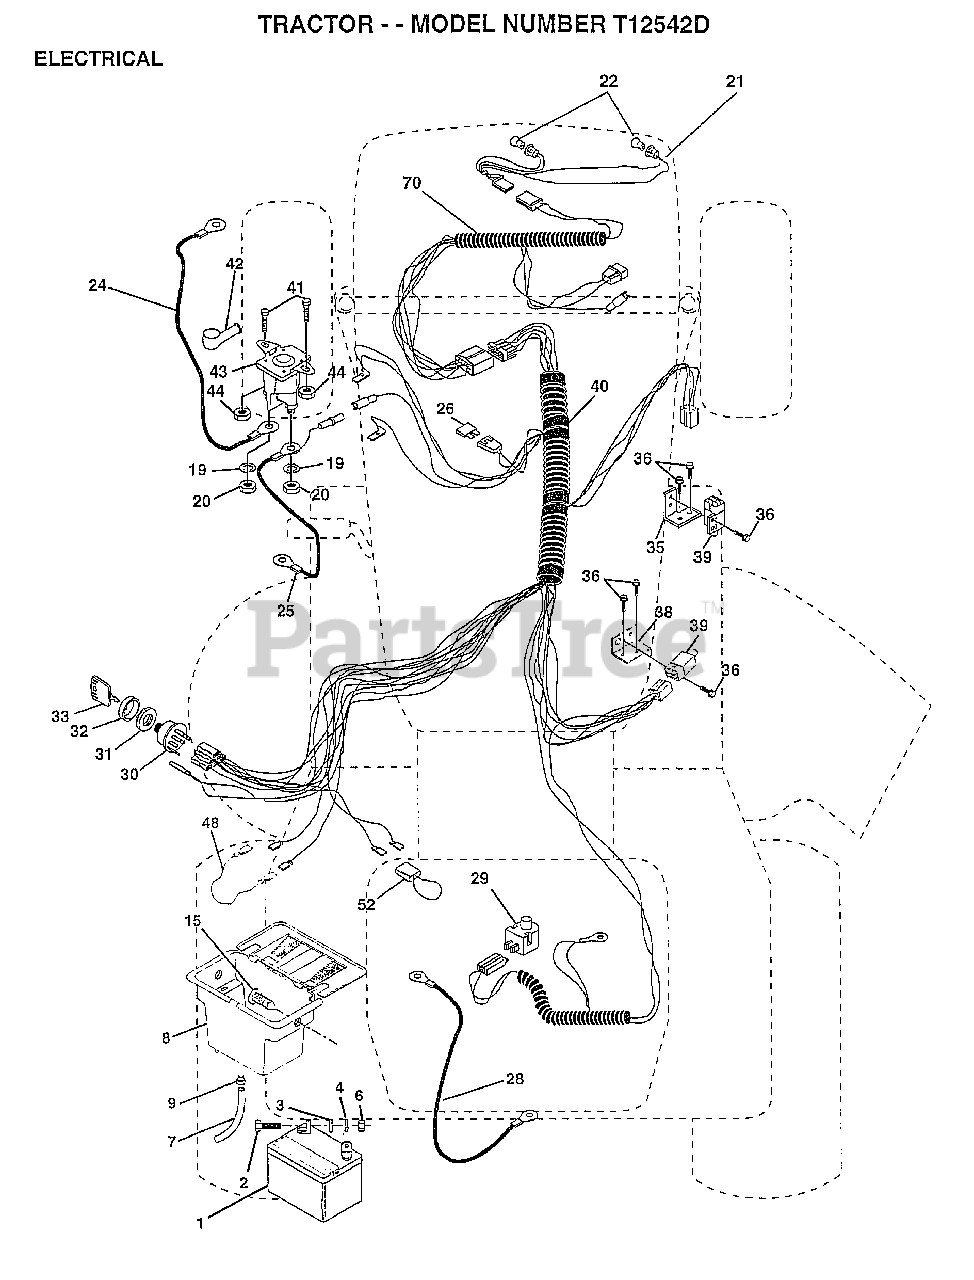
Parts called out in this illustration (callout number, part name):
3	WASHER
4	LOCKWASHER
7	TUBE T
9	HOSE CLAMP T
15	FASTNER.SNAP-IN
20	NUT
21	"HARNESS,LIGHT SOC"
22	HEADLAMP BULB
24	"CABLE T, BATTERY"
25	CABLE.BTRY.6GA.RD
26	FUSE HYT
28	CABLE T
29	SWITCH SEAT
30	SWITCH IGN 4POS
31	NUT IGNITION
32	COVER KEY SWITCH
33	KEY
35	BRACKET LT
36	SCREW
38	BRACKET SWITCH IN
39	SWITCH INTERLOCKT
40	HARNESS.IGNITION
41	BOLT HXHD FIN
44	NUT HXKEP 1/4X20
48	ADAPTER AMMETER
52	PROTECTION LOOP
70	HARNESS.ENGINE
